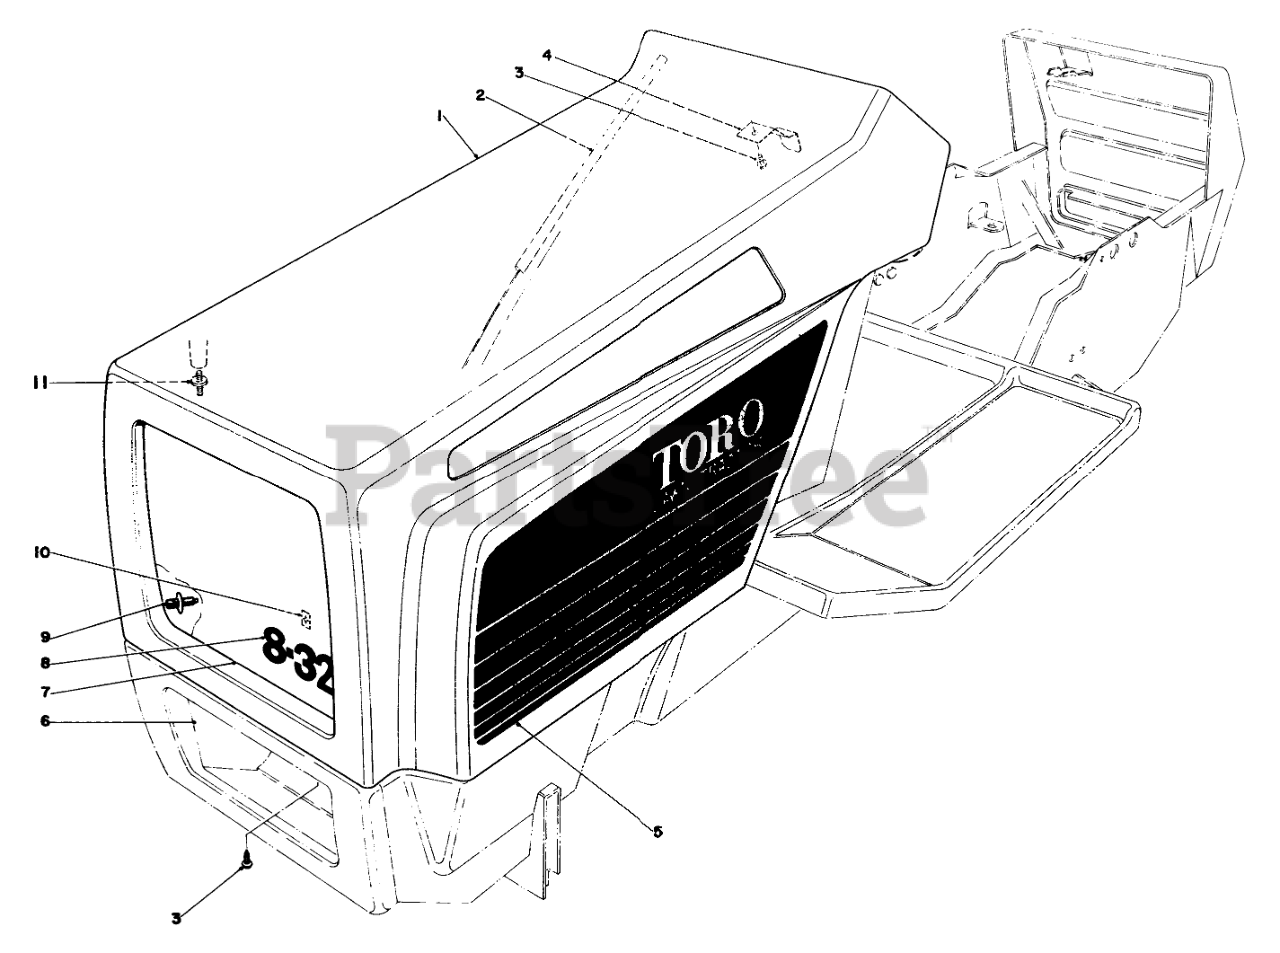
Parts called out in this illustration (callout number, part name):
1	Hood (Incl. Ref. #9 & 11)
2	RUBBER EXT SEAL
3	SCREW-HWHTF
4	SPRING LATCH
5	Decal-Hood L.H.
6	LOWER GRILLE
7	HOOD GRILLE
8	Nameplate Grille
9	HINGE BRKT STUD
11	Stud Hood Duct
